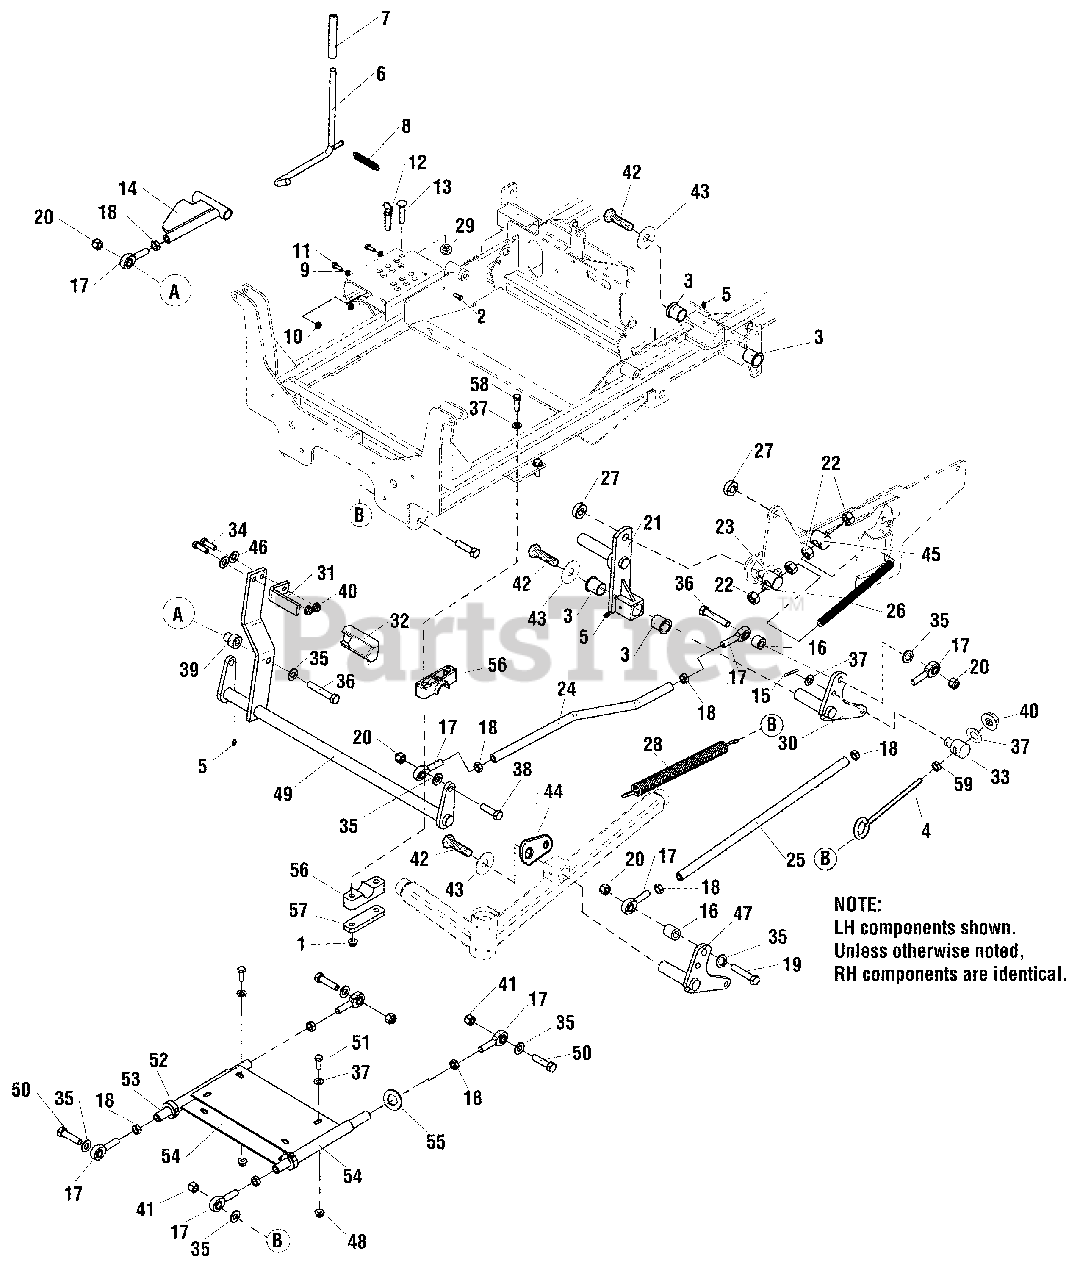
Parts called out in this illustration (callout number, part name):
1	NUT, 3/8-16 HEX NYLOCK FLANGE
2	PIN, CLEVIS, 1/4" x 7/8"
3	BUSHING, 1.00 X 1.13 X 1.38, PLASTIC
4	EYEBOLT, 3/2-16 X 8", 1" EYE
5	GREASE FITTING, 1/4-28 STRAIGHT
6	WELD, ROD DECK LIFT - BLK
7	GRIP, FOAM
8	SPRING, EXTENSION
9	WASHER, 1/4 SAE (5025154)
10	NUT, 1/4-20 HEX SERR. FLANGE
11	BOLT, 1/4-20 X 3/4" GD5 YZ
12	PIN, HITCH, 1/2 X 2.00 OAL, YP
13	BOLT, 3/8-16 X 2", CARRIAGE
14	WELD, DECK ADJUST LINK - ORANGE
15	PIN, COTTER, 1/8" X 3/4
16	SPACER, .52 X 1.00 X .75
17	BALL JOINT, 1/2-20, MALE
18	NUT, 1/2-20 HEX JAM
19	BOLT, 1/2-13 X 2-3/4" GD5
20	NUT, 1/2-13 HEX NYLON LOCK
22	NUT, 5/8-11 HEX
23	PIVOT, SPRING ROD
24	ROD, DECK LIFT BENT
25	ROD, DECK LIFT, OUTER
26	ROD, 5/8-11 X 9.00
27	COLLAR, 5/8" SPLIT
28	SPRING, DECK LIFT ASSIST
29	NUT, 3/8-16 HEX SIDE LOCK
31	PEDAL, FOOT - BLK
32	RUBBER, FOOT PEDAL
33	ADJUSTER, DECK HANGER
34	BOLT, 3/8-16 X 1-1/4" GD5
35	WASHER, 1/2" SAE
36	BOLT, 1/2-13 X 3-1/2" GD5
37	WASHER, 3/8 SAE
38	BOLT, 1/2-13 X 1-3/4" GD5 YZ
39	ADAPTER, CASTER AXLE
40	NUT, 3/8"-16 HEX NYLON LOCK
41	NUT, 1/2-20 HEX NYLON LOCK
42	WASHER, .390 X 1.50 X .109, YZ
43	BOLT, 3/8-16 x 3/4, GD5, YZ WITH PATCH
44	MOUNT, SPRING DECK LIFT - ORANGE
45	PIVOT, SPRING ROD
46	WASHER, 3/8" GR9 FLAT
47	WELD, PIVOT DECK LIFT - LH - ORANGE
48	NUT, 3/8-16 HEX SERRATED FLANGE
49	WELD, DECK LIFT SHAFT - ORG
50	BOLT, 1/2-20 X 1-3/4" GD5 YZ
51	BOLT, 3/8-16 X 1" GD5 YZ
52	COLLAR, 3/4" SPLIT
53	SHAFT, DECK STABILIZER
54	WELD, DECK STABILIZER - BLK
55	WASHER, 1/2 SAE
56	PIVOT BLOCK, PLASTIC
57	PLATE, PIVOT BLOCK SUPPORT - BLK
58	BOLT, 3/8-16 X 2-3/4 GD5 YZ
59	NUT, 3/8-16 HEX
